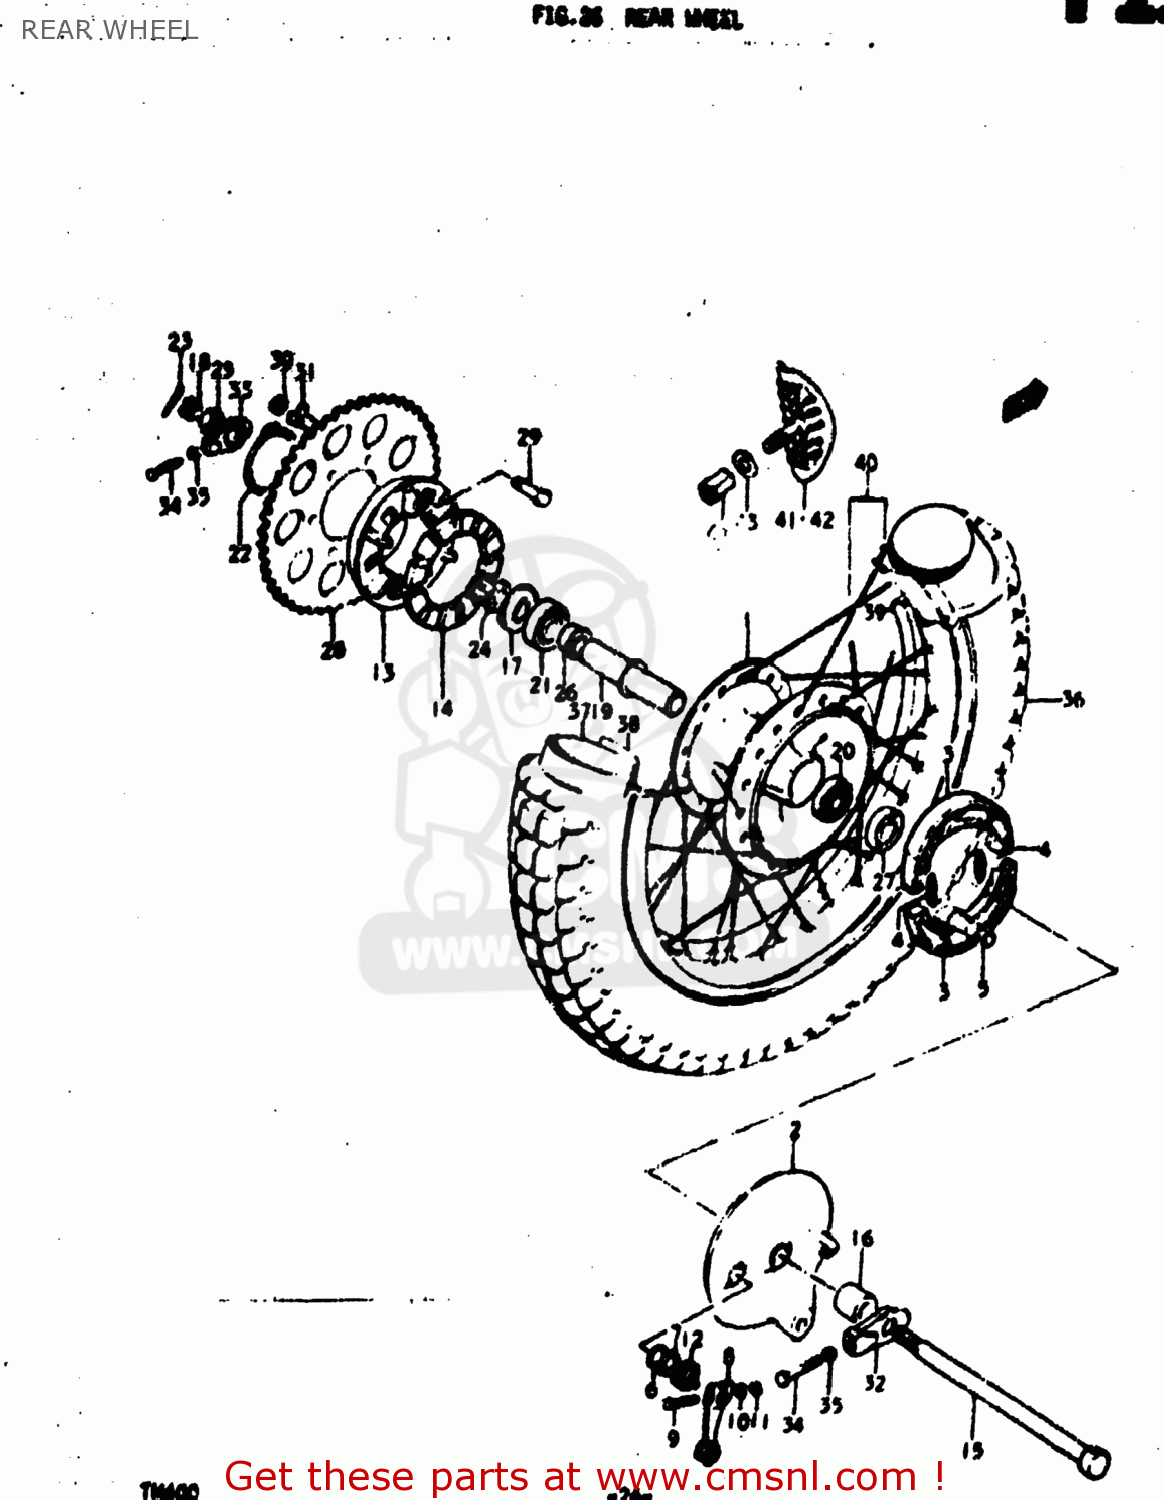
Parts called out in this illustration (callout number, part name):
1	DRUM,REAR HUB
2	PANEL,REAR HUB
3	SHOE,BRAKE
4	SPRING,BRAKE SHOE
5	CAM,FRONT BRAKE
6	O RING(D:1.9,ID:18.8)
7	WASHER (15X24X1.6)
8	LEVER,REAR BRAKE CAM
9	BOLT
10	WASHER
11	NUT
12	SPRING
13	DRUM,REAR SPROCKET MOUNT
14	ABSORBER,RR WHEEL HUB SHOCK
15	AXLE,REAR
16	SPACER
17	SPACER,REAR AXLE,RIGHT
18	NUT
19	SPACER,REAR HUB BEARING
20	BEARING, RH
21	BEARING
22	CIRCLIP
23	PIN 30X40
24	SPACER,REAR AXLE,LEFT
25	NUT
26	SPACER,REAR HUB BEARING
27	OIL SEAL
28	SPROCKET,REAR
29	BOLT(8X33.5)
30	NUT
31	WASHER
32	ADJUSTER,CHAIN
33	ADJUSTER,CHAIN
34	BOLT
35	NUT
36	TIRE
37	TUBE ASSEMBLY,WHEEL,INNER
38	PROTECTOR,WHEEL,INNER
39	RIM,REAR WHEEL
40	SPOKE SET,REAR
41	STOPPER,BEAD
42	STOPPER,BEAD
43	WASHER
44	NUT
